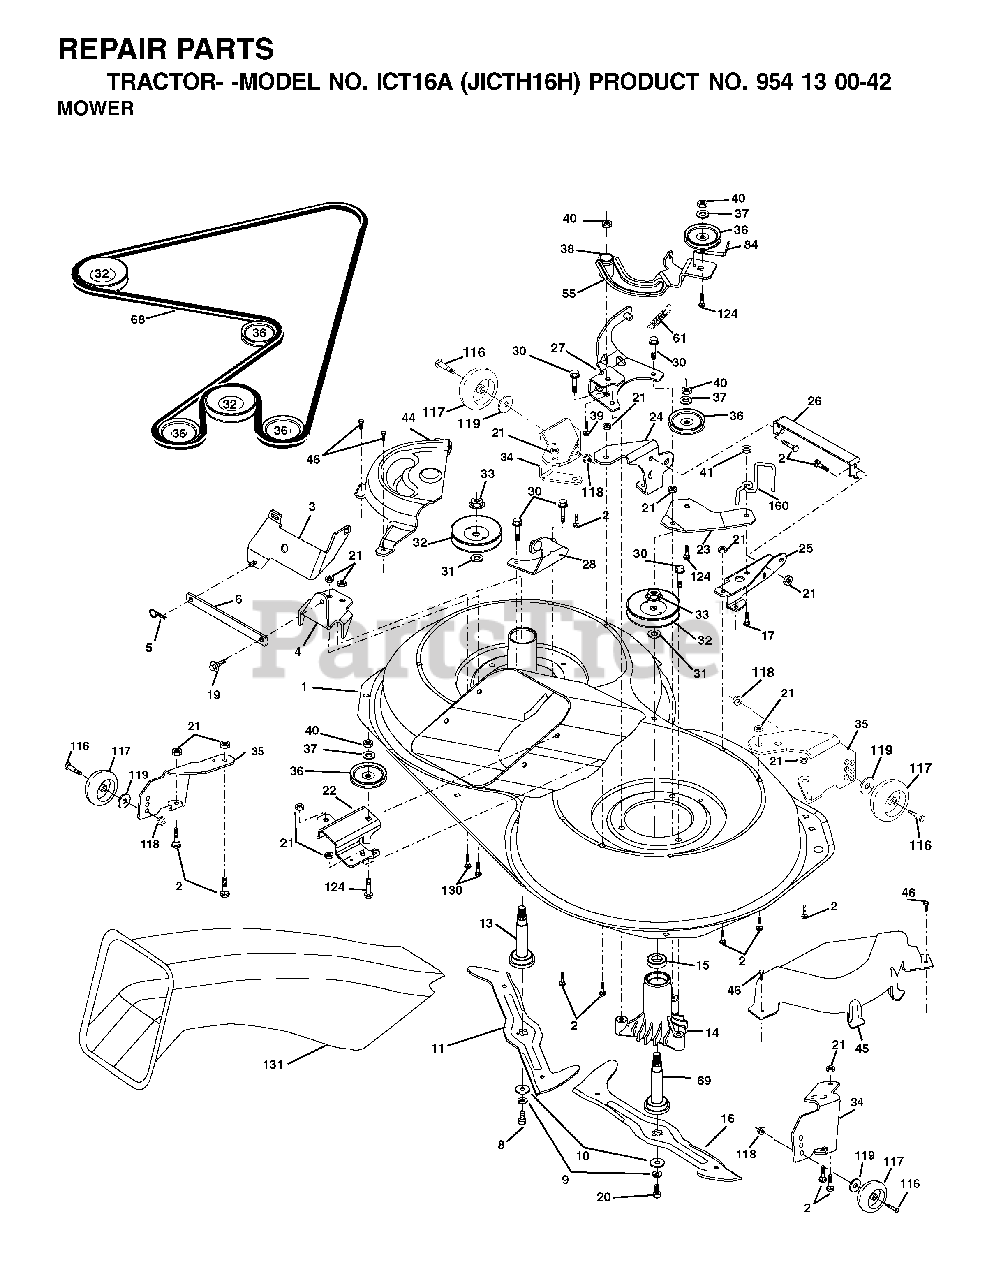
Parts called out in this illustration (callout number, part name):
1	TUBE HANDLE BAGGER
3	NUT T
5	SCREW.PAN.HEAD
10	TUBE
11	BRACKET
14	BOLT
15	RETAINER-SPRNG RB
16	NUT LOCK FLG 3/8-16 UNC
17	BOLT
18	WASHER M
19	NUT LOCK HEX FLANGE 5/16-18
20	BRACKET
21	BAG
22	BRACKET
23	TUBE
24	TUBE
26	TUBE
31	RETAINER M
32	RIVET,DRILLED
33	MULCH PLUG, CTH150
35	PIN
36	WASHER
38	BOLT.5/16-18X2.5
39	TRIM
40	TRIM
41	BRKT, BAGGER
42	NUT.71038.31-18.HEX.NYLOCK
